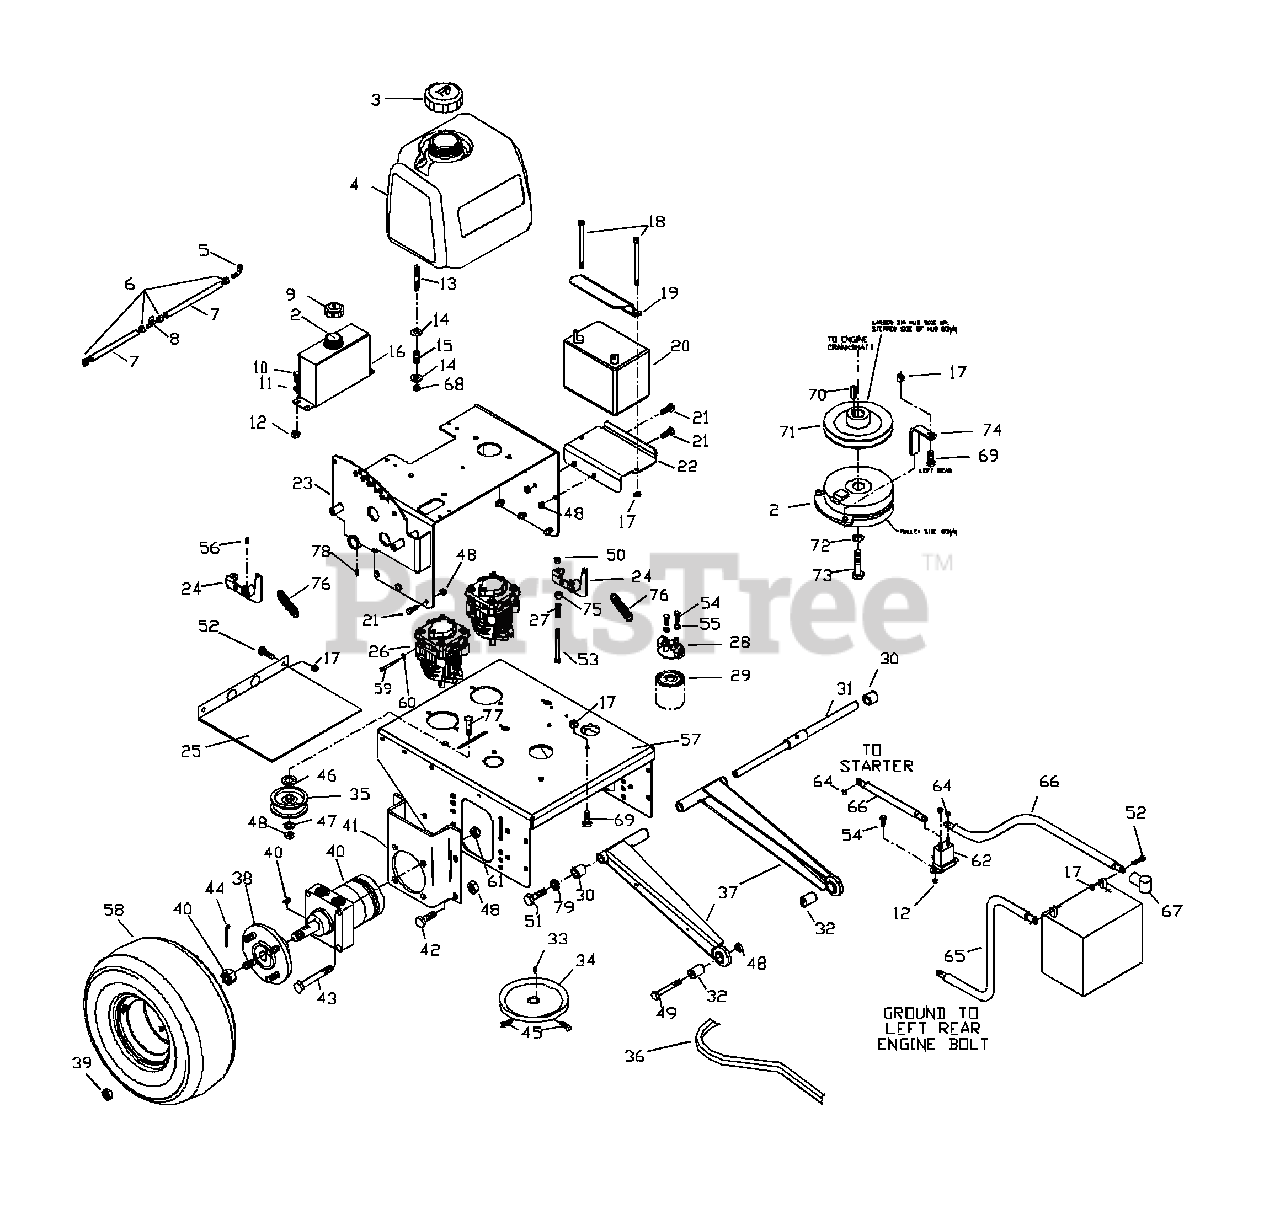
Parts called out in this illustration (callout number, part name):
1	THROTTLE CABLE
3	FUEL CAP
5	FUEL FITTING
6	HOSE CLAMP
8	FUEL VALVE
10	HCS 1/4 X .750
11	WASHER 1/4 FLAT
12	NUT 1/4 CTR. LOCK
14	WASHER 5/16 FLAT
17	NUT 5/16 CTR. LOCK
18	HCS 5/16 X 7.500
19	BATTERY STRAP
20	BATTERY
21	HCS 3/8 X .750
22	BATTERY TRAY
23	TANK SUPPORT
25	BELT SHIELD
26	PUMP
28	FILTER HEAD
31	STRUT SHAFT
32	SPACER, FRONT
33	KEY, METRIC
35	IDLER PULLEY
40	HYD. MOTOR
41	MOTOR MOUNT
42	HCS 3/8 X 1.000
43	HCS 3/8 X 2.750
44	COTTER PIN
45	SET SCR. 5/16
46	WASHER 1/2 FLAT
47	WASHER 3/8 FLAT
48	NUT 3/8 CTR. LOCK
49	HCS 3/8 X 2.250
50	NUT 3/8 NYLOC
51	HCS 1/2 X 1.00
52	HCS 5/16 X .750
53	HCS 3/8 X 2.750
54	HCS 1/4 X .625
55	WASHER 1/4 LOCK
56	SET SCR. 5/16
58	TIRE /WHEEL ASM.
58	RIM
59	CLEVIS PIN
61	NUT 1/2 NYLOC
64	NUT 1/4 NYLOC
66	POS. CABLE
68	NUT 5/16 NYLOC
69	HCS 5/16 X 1.750
70	KEY 1/4 X 1.125
72	WASHER 7/16 LOCK
73	HCS 7/16 X 2.500
77	RHSNB 3/8 X 2.000
78	ZERK
79	WASHER 1/2 LOCK
